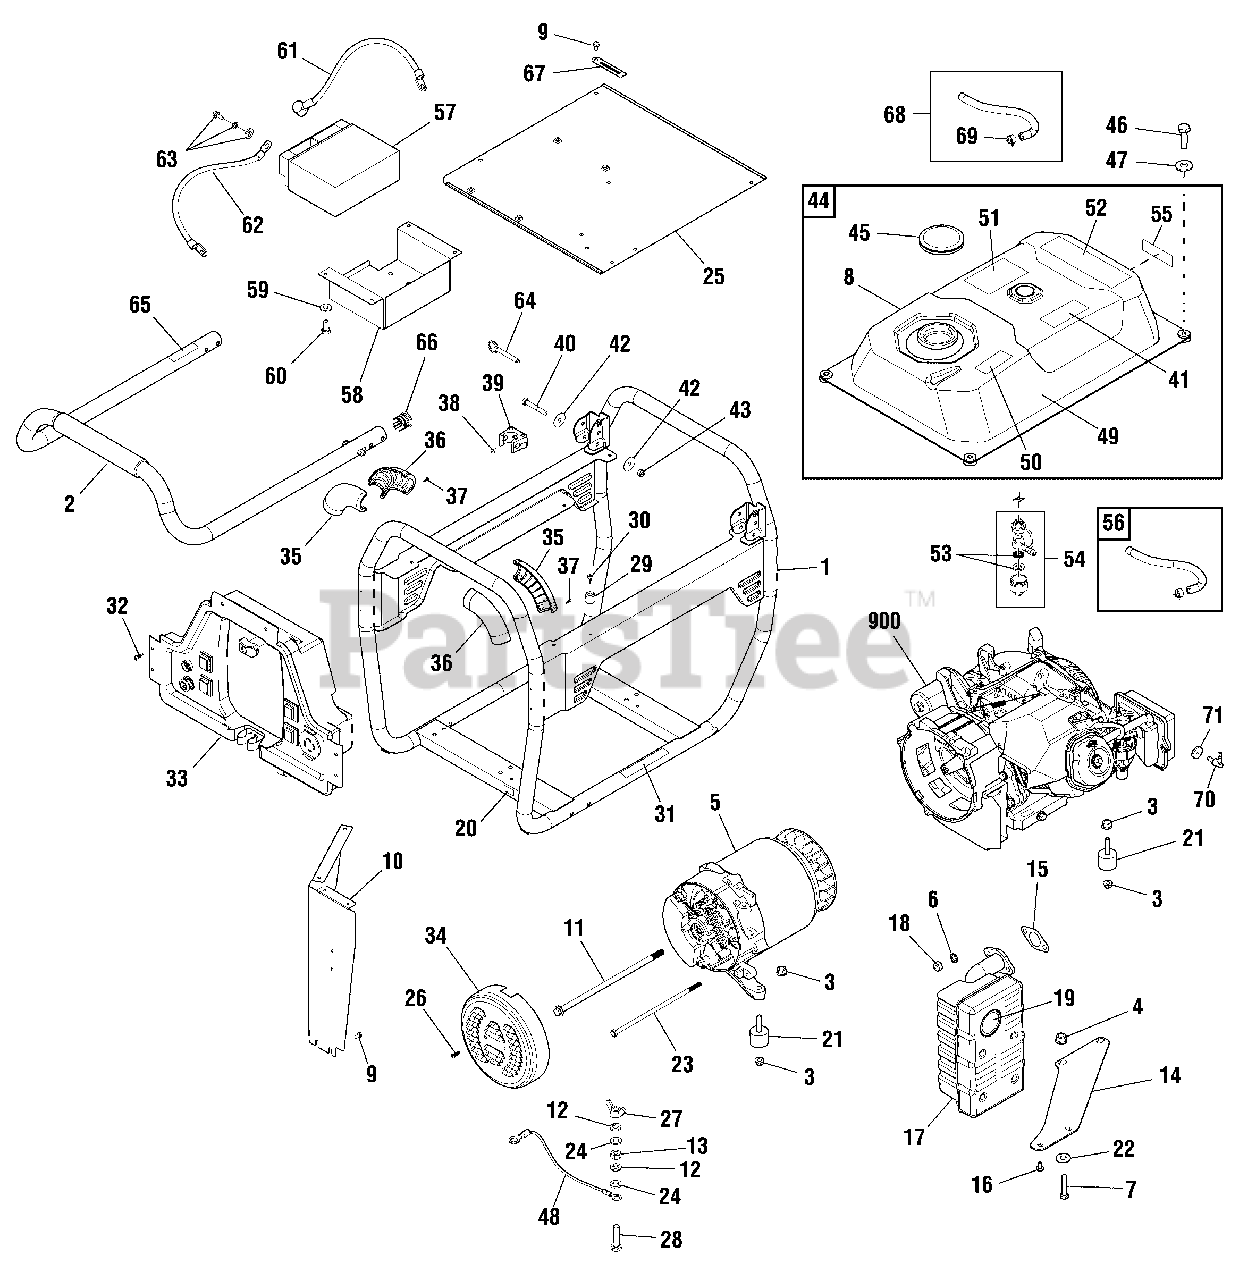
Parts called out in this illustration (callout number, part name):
5	ALTERNATOR
6	* WASHER, Lock, 3/8
7	* CAPSCREW, Hex Head, M10 - 1-1/2 x 45
9	* CAPSCREW, Hex Head, M6-1 x 10
12	* WASHER, Lock, 1/4
13	* NUT, M6-1
15	GASKET, Exhaust
16	* CAPSCREW, Hex Head, M6-1 X 12
18	* NUT, M8 - 1-1/4
21	MOUNT, Vibration
22	WASHER
24	* WASHER, M6
28	* CAPSCREW, Hex Head, M6-1 x 25
34	COVER, Rear Bearing
41	DECAL
47	* WASHER, Flat, 1/4
53	KIT, Fuel Valve Repair
56	KIT, Fuel Hose
63	KIT, Battery Hardware
68	HOSE
900	** ENGINE
